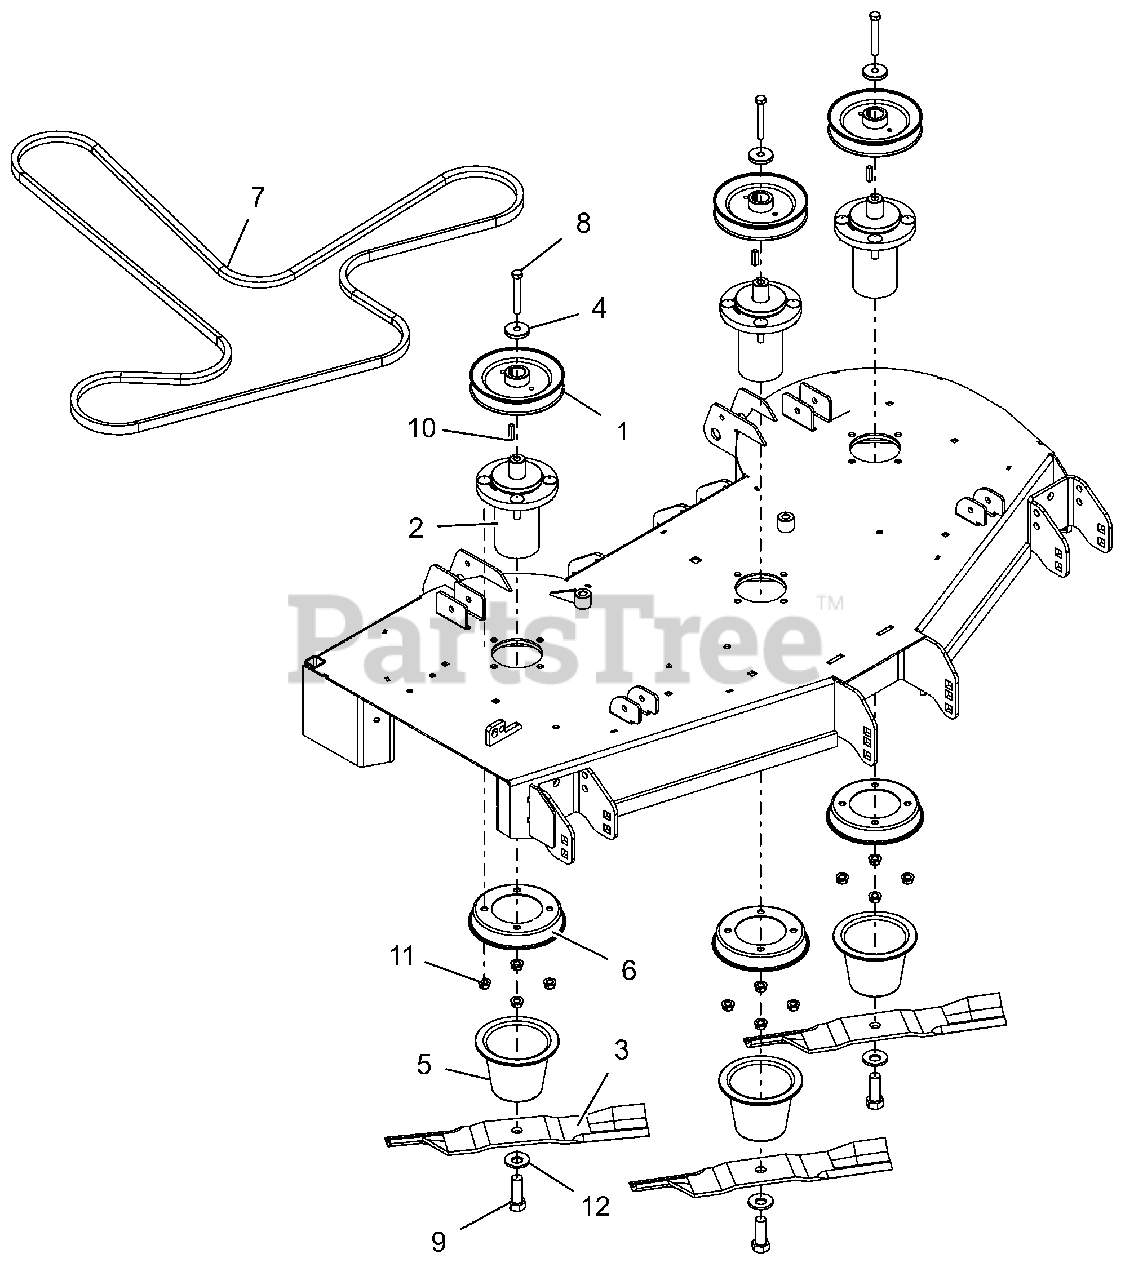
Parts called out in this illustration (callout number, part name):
1	PULLEY, V-1.00 ID X 5.75 OD (BLACK)
2	ASM, MAINT FREE ALUM SPINDLE
3	BLADE, 16.19" MOWER (HI-LIFT)
4	RETAINER, SHEAVE
5	GUARD, SPINDLE LOWER
6	GUARD, SPINDLE TOP
7	V-BELT, B RAW EDGE EPDM
8	BLT-HEX .38-16X2.75 GR8 YWZC
9	BLT-HEX .62-18X1.75 GR8 YWZC
10	KEY, SQ .25X.25X1.00 RC 40-50
11	NUT-LK-CTR-FLG .38-16 YWZC
12	WSHR-BLVL .669X1.535X.138
